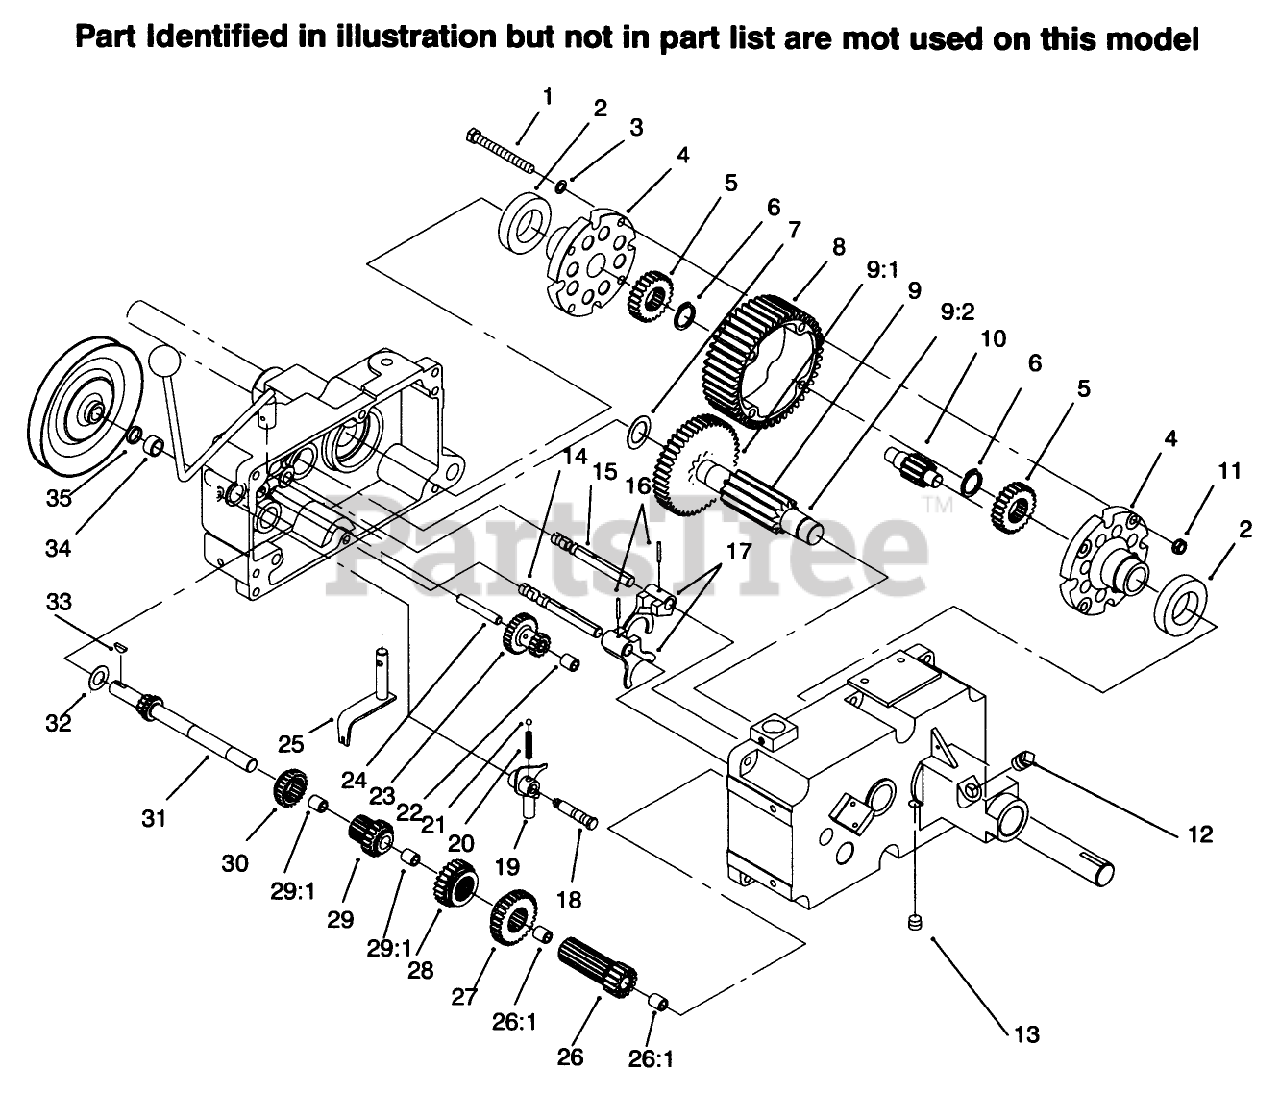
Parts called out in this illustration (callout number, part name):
2	BEARING-BALL
3	WASHER
4	END CAP-DIFFERENTIAL
5	GEAR-AXLE DIFFERENTIAL
6	RING-SNAP
8	GEAR-DIFFERENTIAL RING, 43T
9	GEAR ASM
9:9	PINION SHAFT
10	GEAR-PINION, 11T
11	NUT-HEX
12	PLUG-PIPE, SQH
14	RAIL-SHIFT
14	GEAR-SHAFT REDUCTION
15	RAIL-REAR SHIFT
16	PIN-ROLL
17	FORK-SHIFT
18	BOLT-DETENT
21	BALL-DETENT
22	BEARING-NEEDLE
24	SHIFT ASM
24:1	Shift Lever
24:2	Shaft-Lever
26	GEAR
26:1	BEARING-NEEDLE
27	GEAR-LOW AND REVERSE
28	GEAR-HI AND 2ND
29	GEAR
29:1	BEARING-NEEDLE
31	SHAFT-INPUT
32	WASHER-THRUST
33	KEY-WOODRUFF
34	BEARING-NEEDLE
35	SEAL-OIL
56	GEAR-SLIDING
